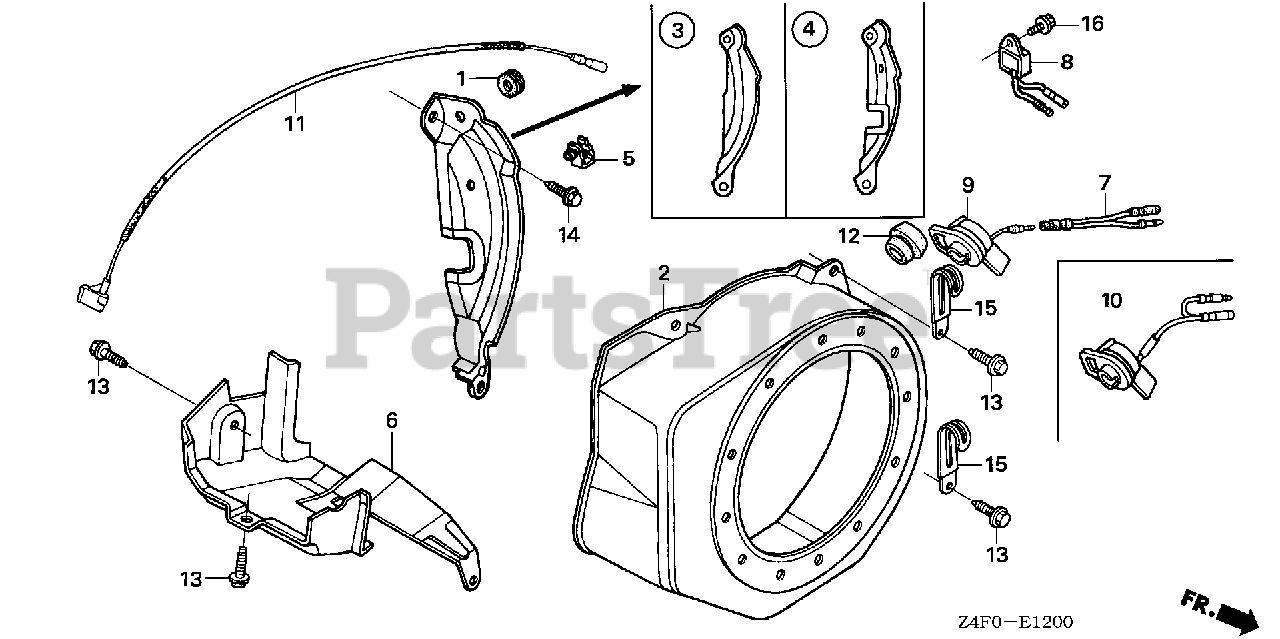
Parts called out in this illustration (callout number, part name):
1	GROMMET, ADJUSTING COVER
2	COVER, FAN *NH1* (BLACK)
2	COVER, FAN *NH246* (LOOSY GRAY)
2	COVER, FAN *R280* (POWER RED)
3	PLATE, SIDE (OIL ALERT)
5	CLIP, HARNESS
8	ALERT UNIT, OIL
10	SWITCH ASSY., ENGINE STOP
11	WIRE, STOP SWITCH (370MM)
13	BOLT, FLANGE (6X12) (CT200)
14	BOLT, FLANGE (6X20) (CT200)
16	BOLT, FLANGE (6X8)
